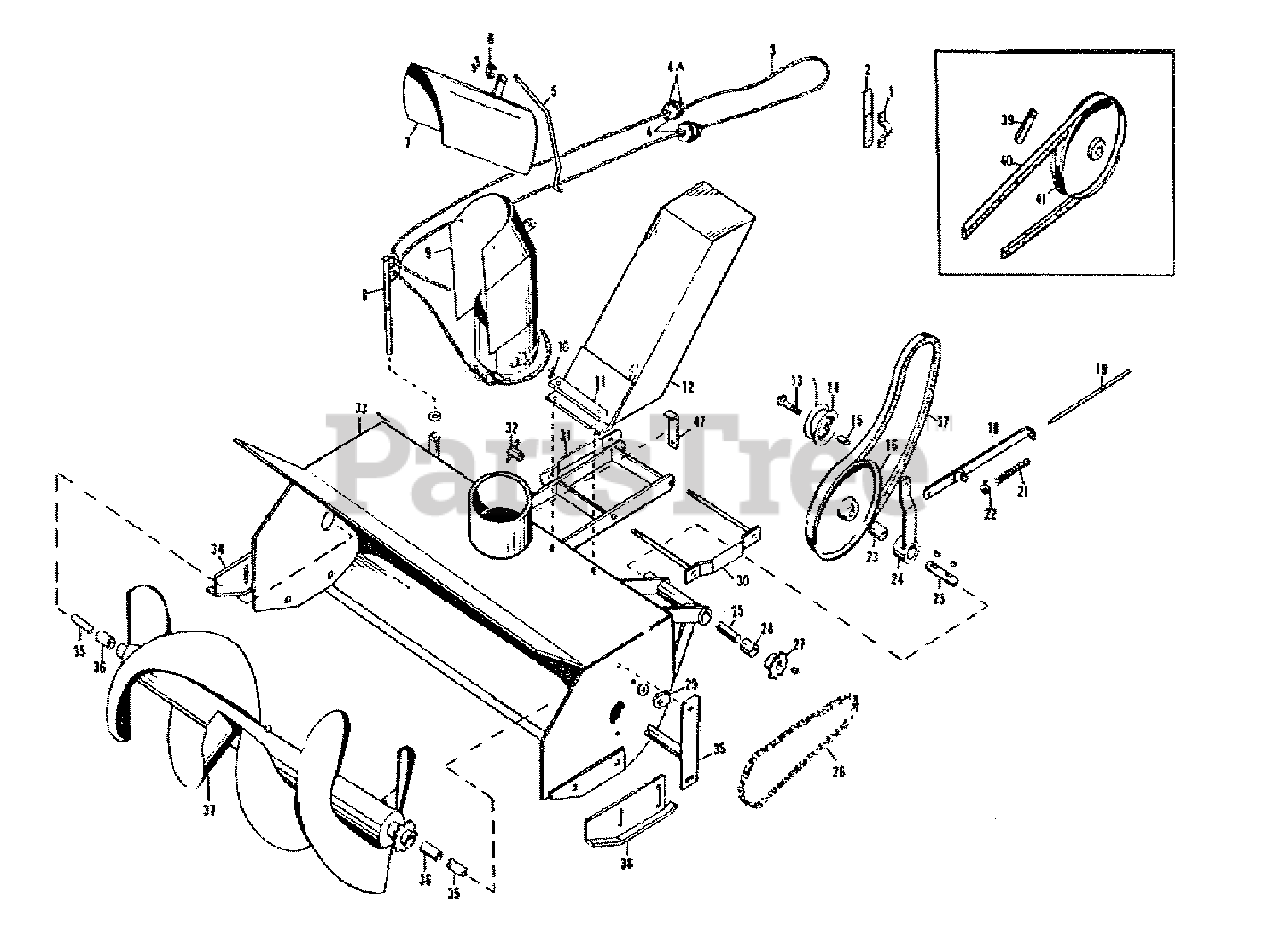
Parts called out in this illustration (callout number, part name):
1	STRAP, Handle
2	STRAP, Cord
3	CORD, Spout
5	ROD, Spout Ext. Adjustment
6	CLAMP, Spout Rod
7	EXTENSION, Spout Assembly
8	ROD ASSEMBLY, Cord
9	SPOUT ASSEMBLY
10	CLAMP, Spout Cord
11	CLAMP, Belt Guard
12	GUARD, Belt Assembly
13	BOLT, Idler Pulley
14	PULLEY, Idler
15	RACE, Inner Bearing
16	SHEAVE, Drive
17	V" BELT, 44
18	GUIDE, Idler Clutch Rod Assembly
19	ROD, Idler Clutch
20	CLIP, Spring
22	COLLAR, Set
23	BEARING, Bearing Housing
24	LEVE, Idler Assembly
25	SHAFT, Drive
26	CHAIN, Rotor
28	BEARING, Bearing Housing
29	TIGHTENER, Chain
30	CLAMP, Hitch Assembly
31	PLATE, Hitch Side
33	BODY AND PUSH ARM ASSEMBLY
34	SHOW ASSEMLBY, R.H.
35	SHAFT, Rotor Assembly
36	BEARING, Rotor
37	ROTOR ASSEMBLY
38	SHOE ASSEMBLY, L.H.
39	STOP, Transmission Idler Lever
40	BELT, A-Sect, 47.30
47	HOLD DOWN, Spout Sleeve
